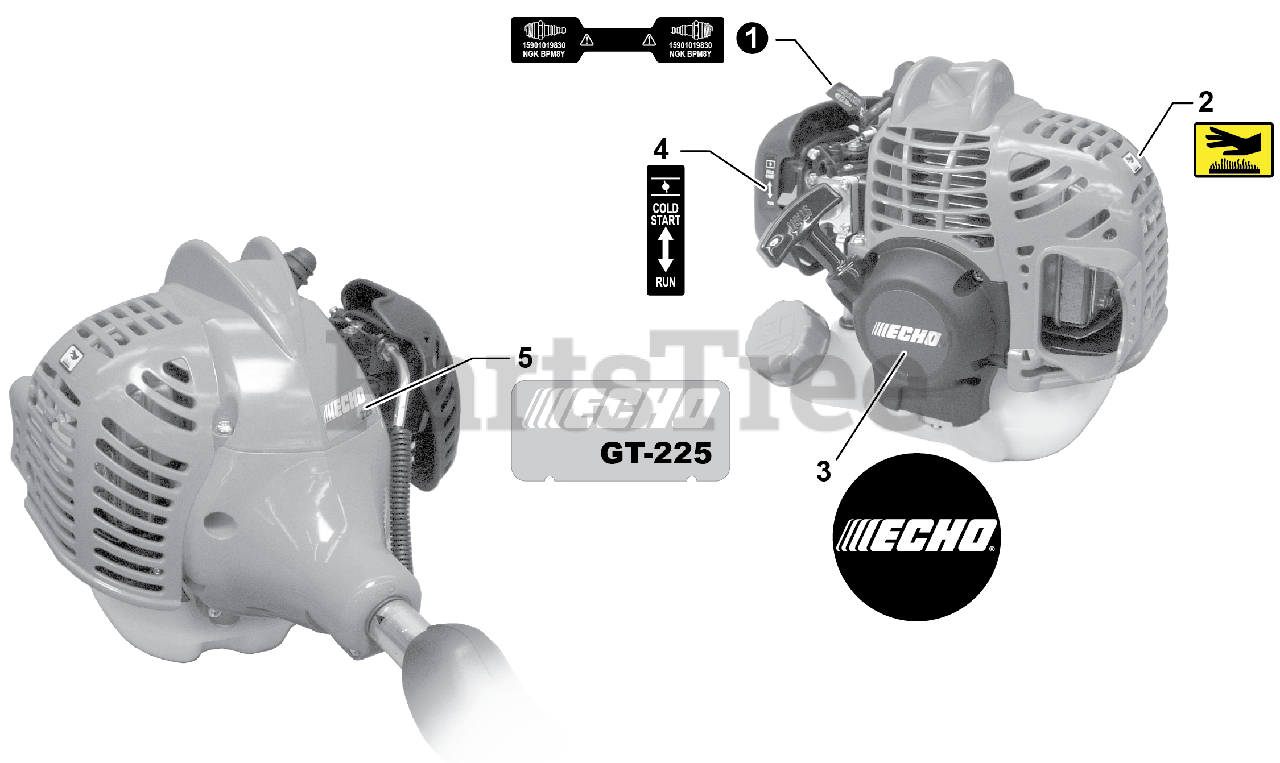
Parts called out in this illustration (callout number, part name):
1	LABEL, SPARK PLUG - BPM8Y
2	LABEL, CAUTION - HOT
3	LABEL, RECOIL STARTER
4	LABEL, CHOKE
5	LABEL, MODEL - GT-225
